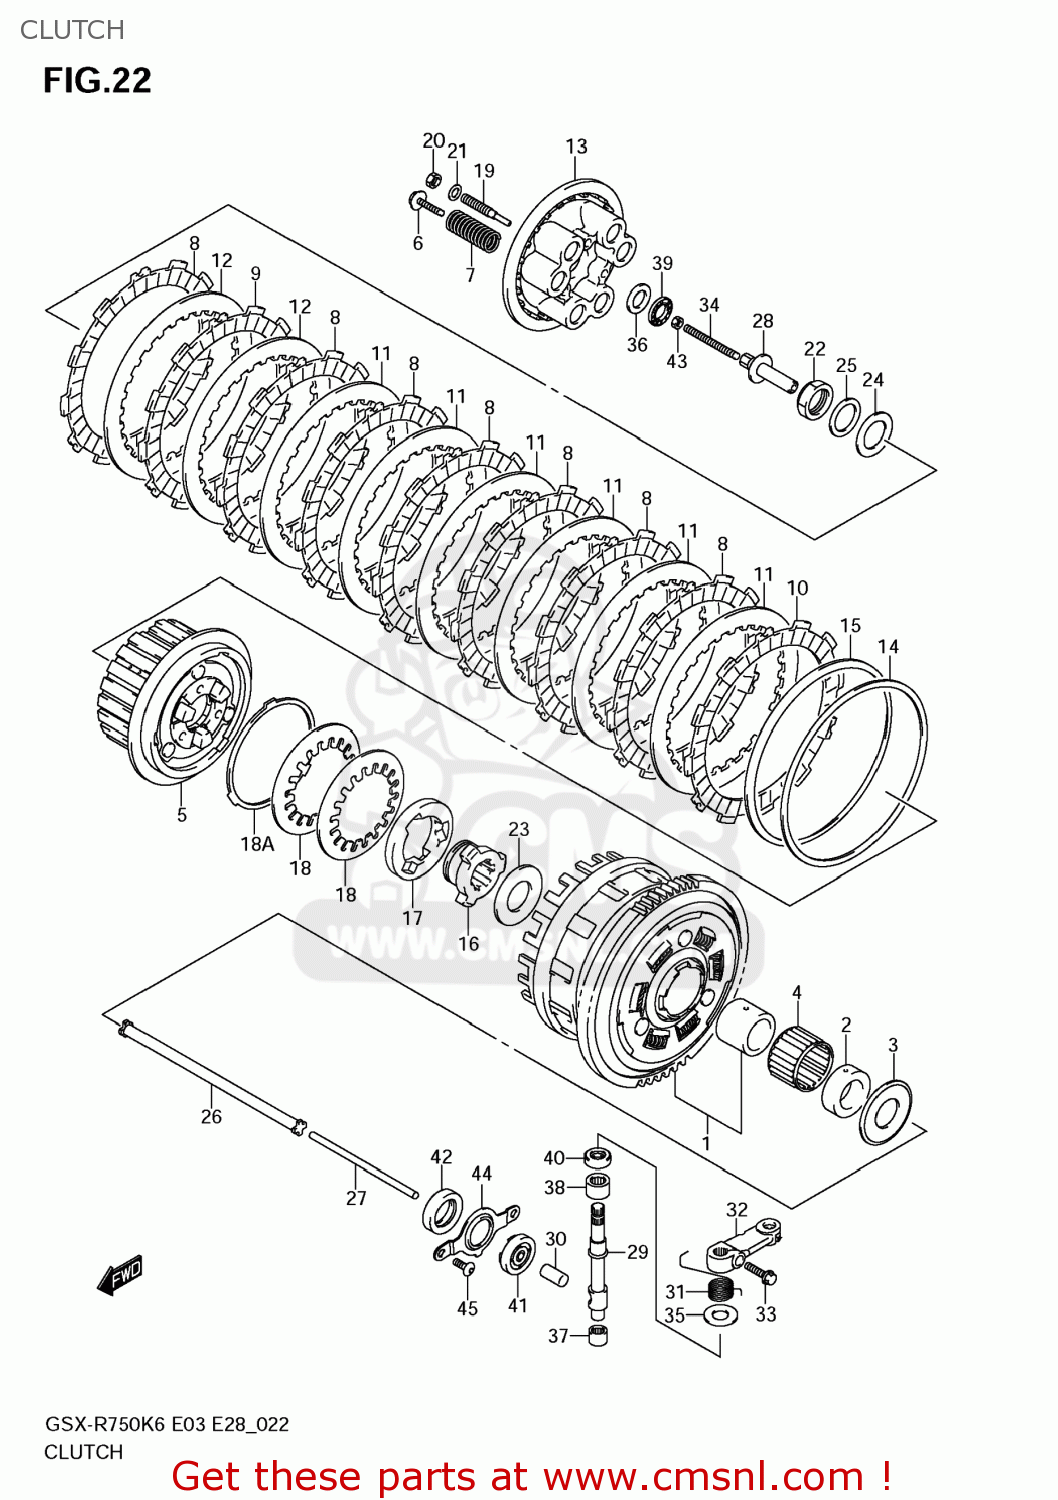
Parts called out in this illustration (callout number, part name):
1	GEAR ASSY,PRIM
2	SPACER,OIL PUMP DRIVE SPROCKET
3	WASHER(25X54X2.4)
4	BEARING(35X40X26.8)
5	HUB,CLUTCH SLEEVE
6	BOLT,CLUTCH SPRING
7	SPRING,CLUTCH
8	PLATE,CLUTCH DRIVE NO.1 (NAS)
9	PLATE,CLUTCH DRIVE (NAS)
10	PLATE,CLUTCH DRIVE NO.3 (NAS)
11	PLATE,CLUTCH DRIVEN (NAS)
12	PLATE,CLUTCH DRIVEN (NAS)
13	DISC,CLUTCH PRESSURE
14	SEAT,WAVE WASHER
15	WASHER,CLUTCH PLATE WAVE
16	CAM,CLUTCH DRIVE
17	CAM,CLUTCH DRIVEN
18	WASHER,CAM REACTION WAVE
18A	WASHER,CAM REACTION SEAT
19	LIFTER,CLUTCH PRESSURE DISC
20	NUT,CL PRESS DISC LIFTER LOCK
21	SHIM(8.8X14X1)
22	NUT
23	WASHER(25X50X2.5)
24	WASHER
25	WASHER(25X41X2.5)
26	ROD,CLUTCH PUSH,R
27	ROD,CLUTCH PUSH,L
28	PIECE,CLUTCH PUSH
29	CAMSHAFT,CLUTCH RELEASE
30	CAP,CLUTCH PUSH ROD
31	SPRING,CLUTCH RELEASE RETURN
32	ARM,CLUTCH REL
33	BOLT(6X20)
34	SCREW. CLUTCH P
35	WASHER. CLUTCH
36	WASHER(15.5X28X1)
37	BEARING(10X14X10)
38	BEARING(12X18X12)
39	BEARING(15X28X2)
40	SEAL,OIL(10X20X6)
41	SEAL,OIL(6X34X10)
42	SEAL,OIL(10X17X5)
43	NUT
44	RETAINER,CL PUSH ROD OIL SEAL
45	SCREW(6X13)
